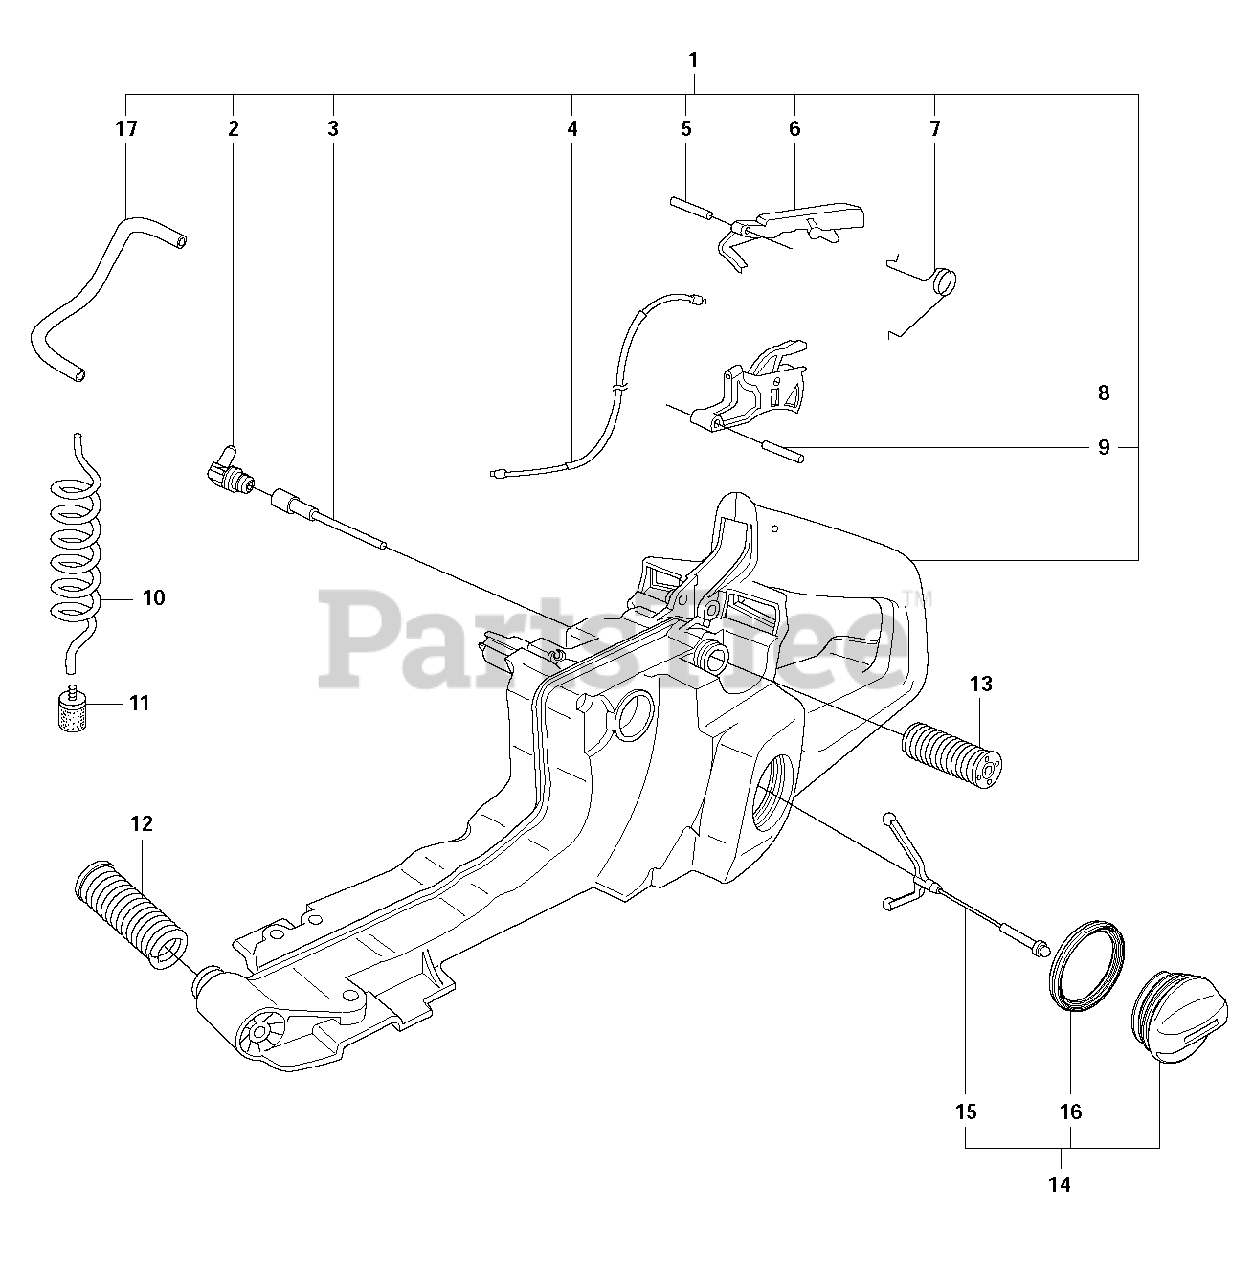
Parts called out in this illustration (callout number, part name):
1	TANK
2	CONNECTOR
3	TANK VALVE
4	WIRE
5	PIN 3X25
6	THROTTLE LOCK
7	SPRING
8	THROTTLE TRIGGER
9	PIN CPH8 4X20
10	FUEL HOSE
11	FUEL FILTER
12	ANTIVIBE MOUNT
12	AV SPRING (HARD)
13	ANTIVIBE MOUNT
14	TANK CAP
15	HOLDER
16	SEALING
17	HOSE
